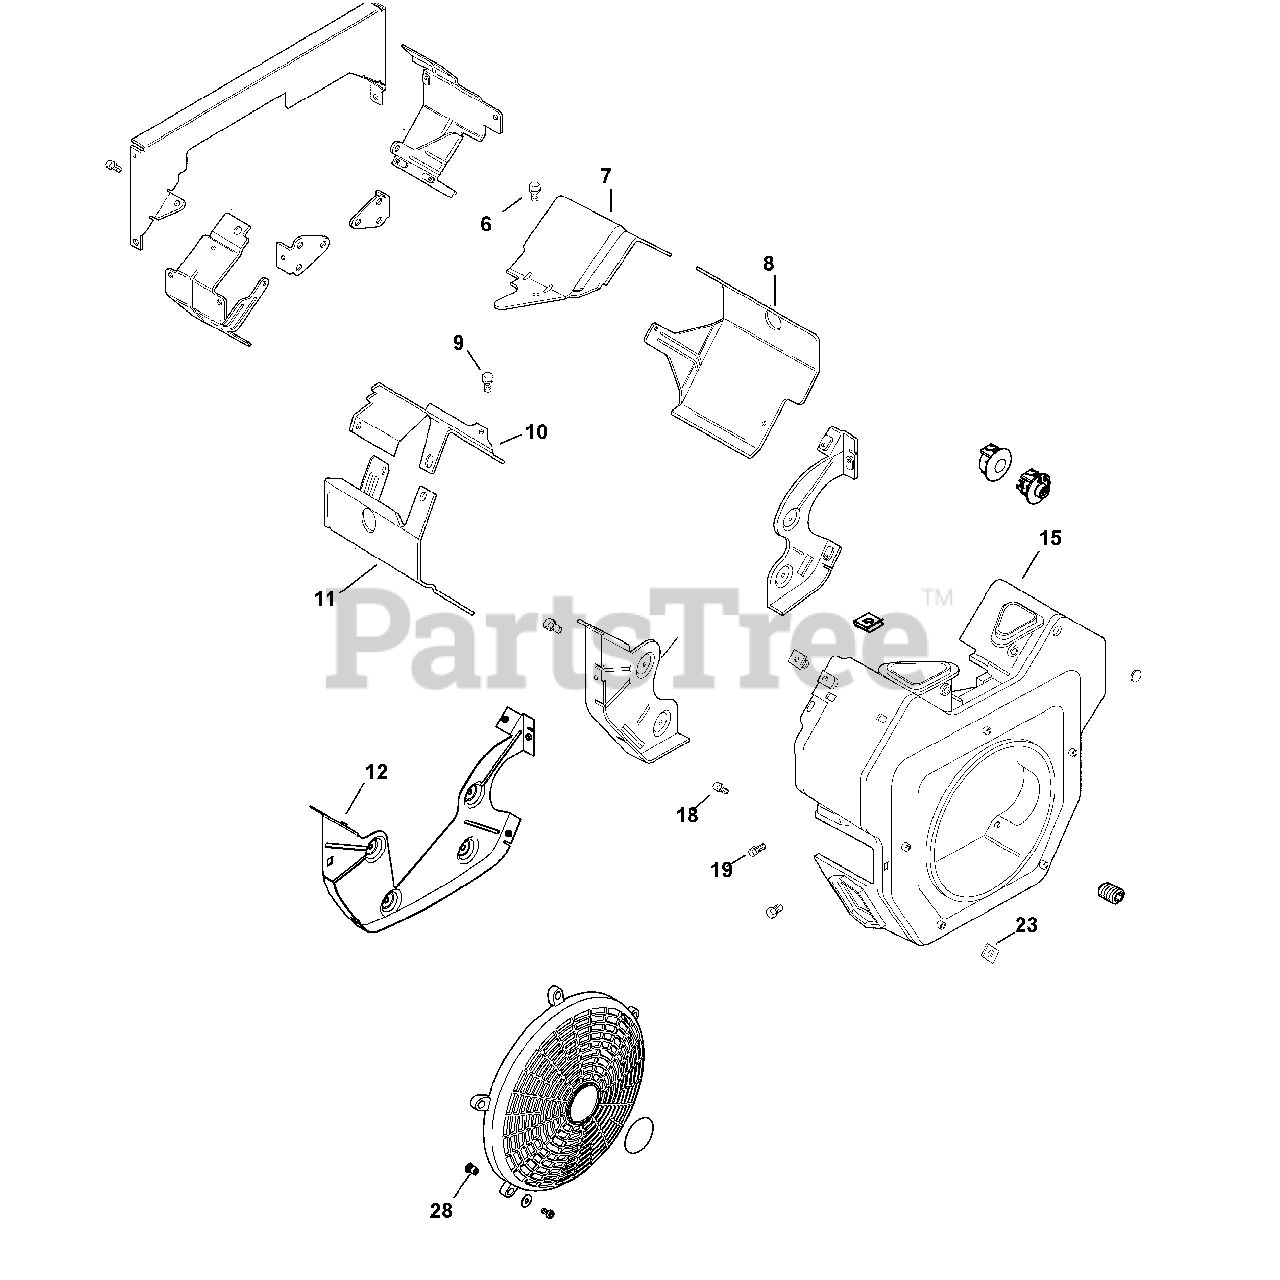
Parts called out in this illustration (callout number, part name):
6	Screw, Thread Forming
7	Baffle, Valley #1 Cyl
8	Kit, Cyl Baffel #1 Side
9	Screw, Thread Forming
10	Baffle, Valley #2 Cyl
11	Kit, Cyl Baffel #2 Side
12	Kit, Backing Plate
15	Kit, Blwr Housing
18	Screw, Thread Forming
19	Screw, Thread Forming
23	Nut, Plastic - Black
28	Insert, Threaded
